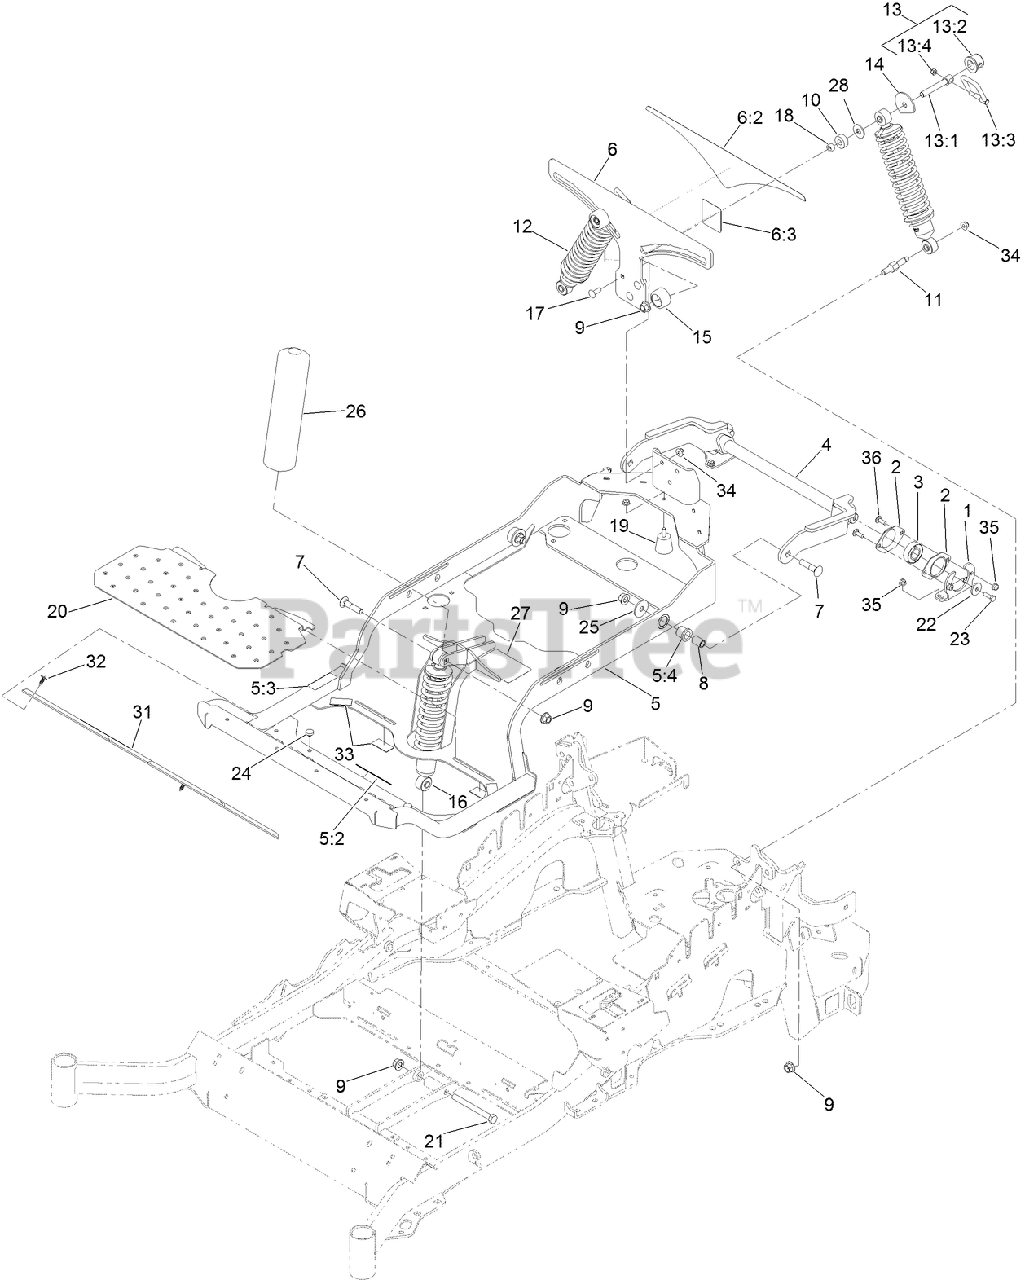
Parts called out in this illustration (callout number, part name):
1	BRACKET-BEARING
2	HOUSING-BEARING, FLANGE
3	BEARING
4	ARM-TRAILING
5	SUBFRAME ASM
5:2	DECAL-DANGER
5:3	DECAL-BRAKE, PARKING
5:4	BUSHING-FLANGE
6	BRACKET-MOUNTING
6:2	DECAL-ADJUSTMENT, RIDE
6:3	DECAL-LOCK, CAM
7	SCREW-CARR
8	SPACER-ALUMINUM
9	NUT-LOCK
10	SPACER
11	BOLT-SHOULDER
12	SHOCK/SPRING ASM
13	CAM LOCK ASM
13:1	SHAFT-LOCK
13:2	CAP-LOCK
13:3	CAM LOCK LEVER ASM
13:4	NUT-HEX
14	PLATE-STOP
15	KNOB-FRONT
16	SHOCK/SPRING ASM
17	SCREW-CARR
18	BEARING-NEEDLE
19	BUMPER-RUBBER
20	FLOORPAN
21	SCREW-HH
22	WASHER-FLAT
23	SCREW-HH, THREAD LOCKING
24	BUMPER
25	WASHER-THRUST
26	COVER-SHOCK
27	DECAL-SERVICE AID
28	WASHER-FLAT
31	MAT-FLOOR
32	PLUG-PLASTIC
33	PAD-RUBBER
34	NUT-HF, NI
35	NUT-HF, NI
36	BOLT-CARR
